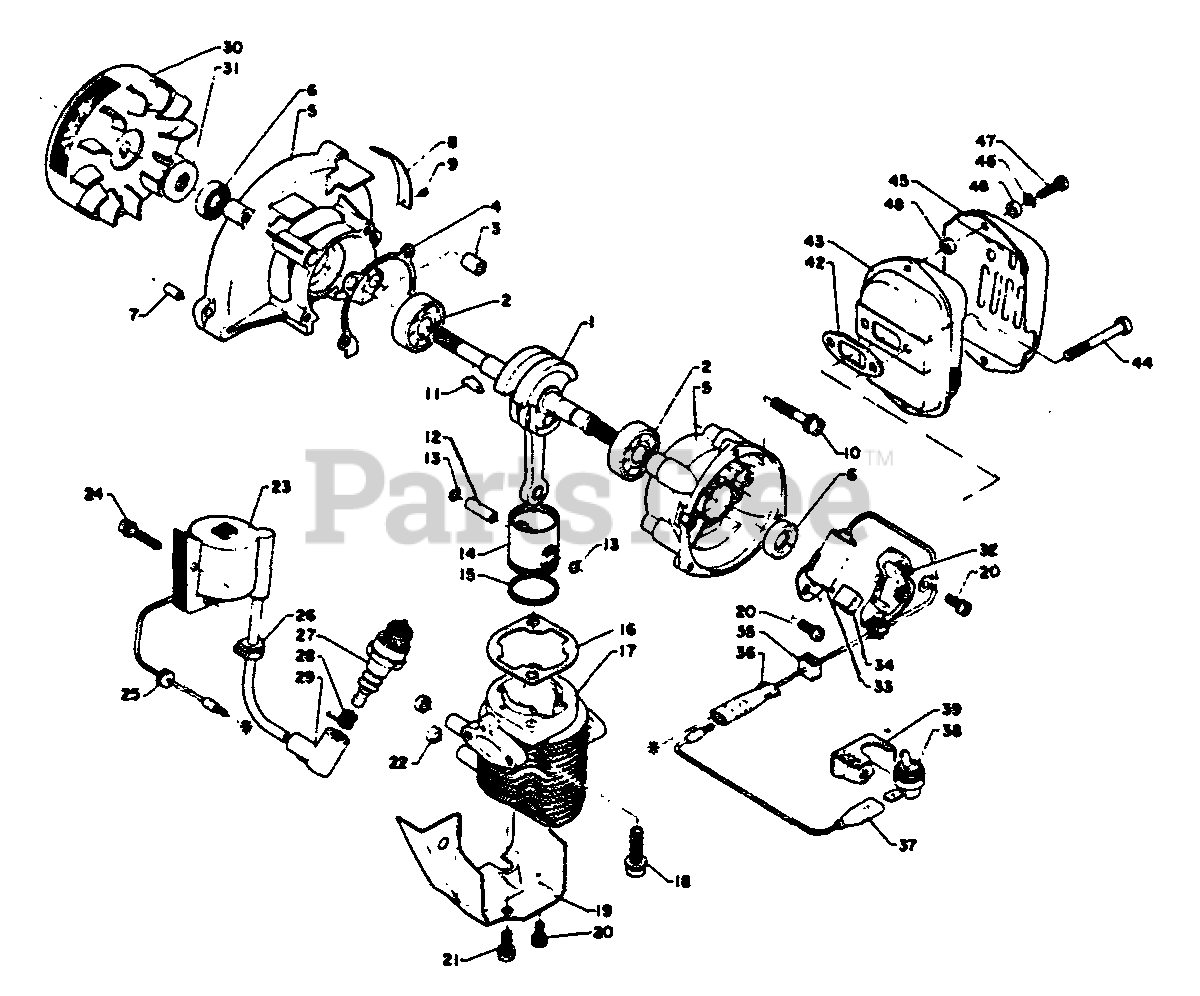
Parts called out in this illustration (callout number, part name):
1	CRANKSHAFT ASSY
2	BEARING, BALL 6200
3	PIN, DOWEL
4	GASKET, CRANKCASE
5	CRANKCASE KIT
6	SEAL, OIL
7	PIN, LOCATING 5×10
8	MODEL PLATE
9	RIVET
10	SCREW 5×30
12	PIN, PISTON
13	RING, RETAINING
14	PISTON
15	RING, PISTON
16	GASKET, CYLINDER
17	CYLINDER
18	SCREW 6×22
19	COVER, ENGINE
20	SCREW - 4×10
21	SCREW 5×10
22	SPACER
23	COIL, IGNITION
24	SCREW 4×22
25	GROMMET
27	SPARK PLUG - BM6A
28	TERMINAL, SPARK PLUG CAP
29	CAP, SPARK PLUG
30	FLYWHEEL
32	CONTACT POINT SET
33	CONDENSER
34	PAD, OIL
35	GROMMET
36	CORD, PRIMARY
37	LEAD - GROUND
38	SWITCH, IGNITION
39	BRACKET, SWITCH
42	GASKET, EXHAUST
43	MUFFLER
44	SCREW 5×42
45	COVER, MUFFLER
46	WASHER 4 MM
47	SCREW 4×14
48	SPACER
